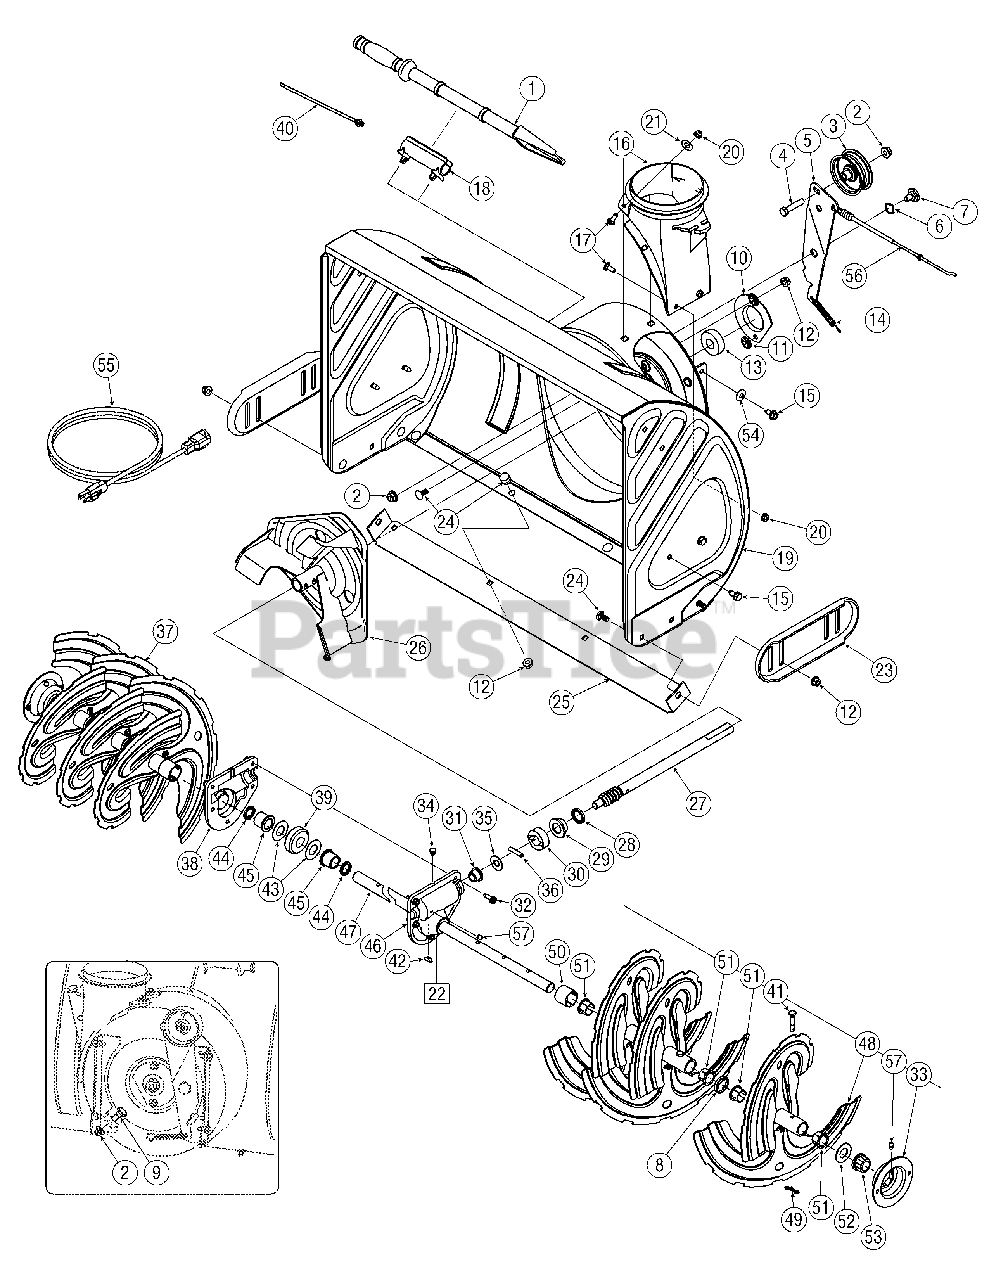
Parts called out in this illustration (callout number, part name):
1	Clean-Out Tool
2	Flange Lock Nut
3	Flat Idler Pulley
4	Hex Bolt, 3/8-16 x 1.75
6	Wave Washer
7	Shoulder Screw
9	Shoulder Screw
10	Bearing Housing
12	Flange Lock Nut, 5/16-18
13	Ball Bearing
14	Extension Spring
15	AB Screw, 5/16-18 x 0.625
16	Chute Adapter
17	Carriage Screw, 1/4-20 x 0.75
18	Clean-out Tool Mtg. Bracket
20	Flange Lock Nut, 1/4-20
21	Flat Washer
22	Gearbox Assembly Complete
24	Carriage Bolt
27	Worm Shaft
29	Flange Bearing
30	Thrust Collar
31	Flange Bearing
32	TT Screw, 1/4-20 x 0.75
35	Flat Washer
38	Reducer Hsg.-RH (Incl Ref.44-45)
39	Worm Gear, 20T
40	Cable Tie
42	Key
43	Flat Washer
45	Flange Bearing
46	Reducer Hsg.-LH (Incl Ref.44-45)
47	Auger Axle
49	Bow Tie Cotter Pin
51	Flange Bushing
52	Flat Washer
53	Hex Flange Bearing
54	Bell Washer
55	Extension Cord
56	Auger Clutch Cable
57	Lube Fitting
